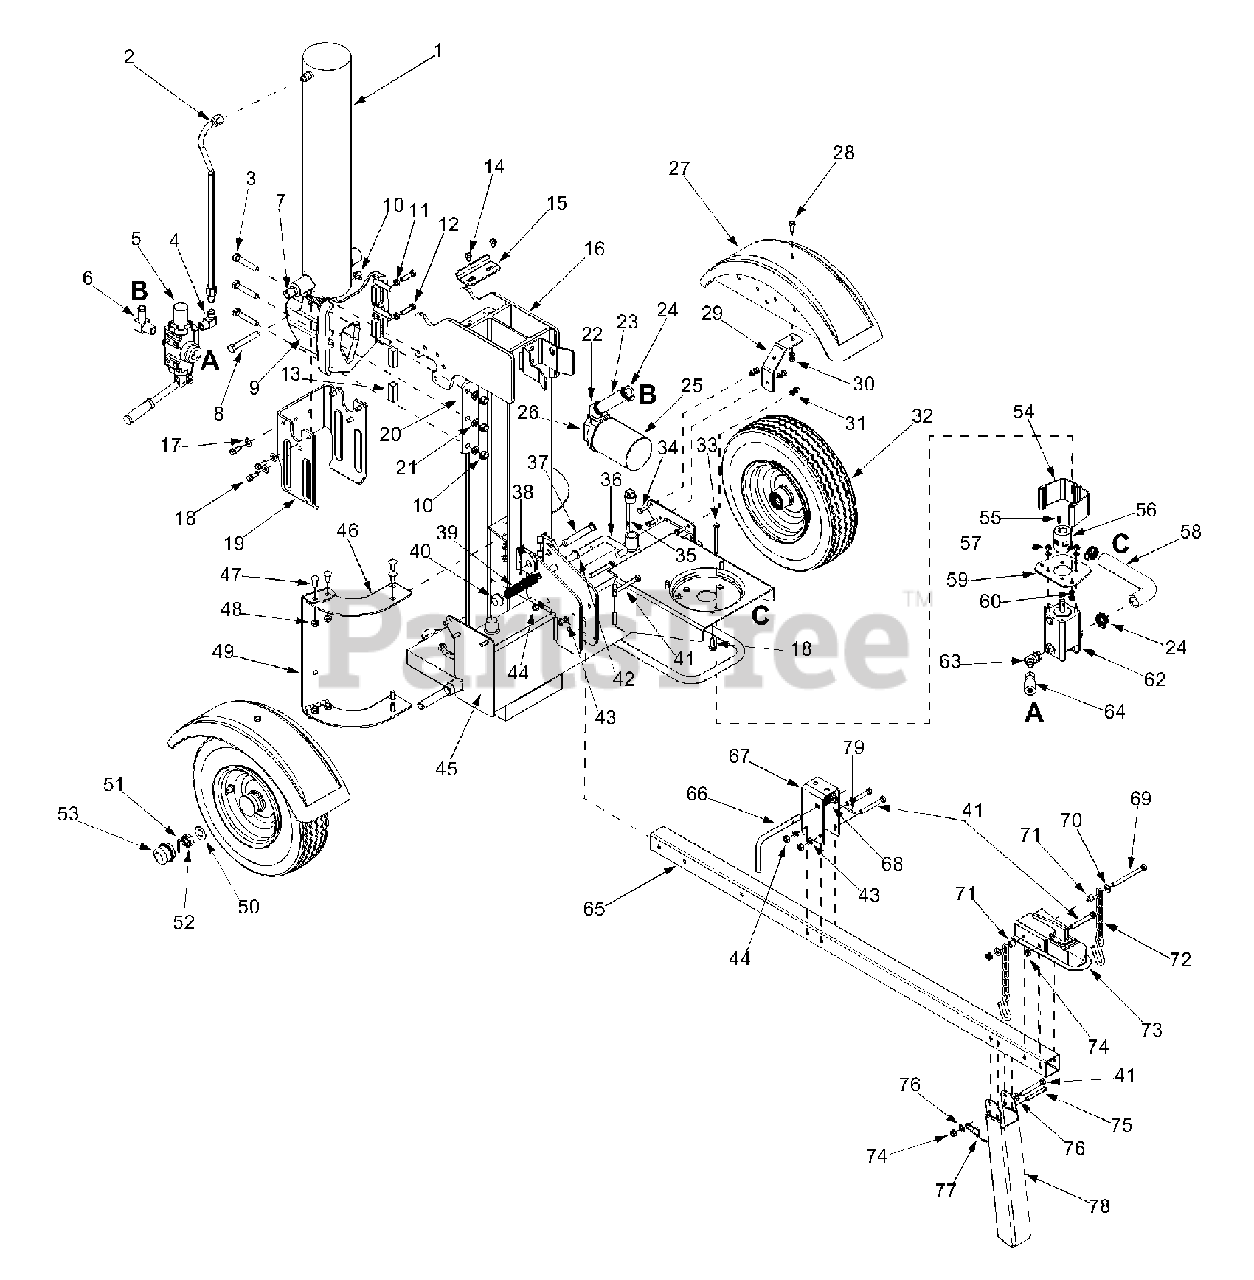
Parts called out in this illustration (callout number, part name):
1	Hydraulic Cylinder
1	Seal Kit 4.5" for Fisher Cylinder 718-0769
1	Kit Seal 4.5" for XINGHUI cylinder 718-0769A
1	Kit Seal 4.5" for ENERGY cylinder 718-0769A
2	Hydraulic Tube
3	Hex Cap Screw 1/2-20 x 2.75
4	90 Degree Solid Adapter
6	Return Elbow
7	Nipple Pipe 1/2-14
8	Hex Cap Screw 1/2-20 x 3.50
9	Wedge Assembly
10	Lock Nut 1/2-20
11	Hex Jam Nut 3/8-24
12	Hex Cap Screw 3/8-24 x 1.5
14	Hex Washer Screw 5/16-18 x .625
17	Flat Washer .406 ID x .875 OD
18	Hex Washer Screw 3/8-16 x 1.0
21	Lock Washer 1/2
22	Adapter 3/4-14
23	Return Hose 3/4" ID x 44" Lg.
24	Hose Clamp 5/8"
25	Oil Filter
26	Filter Housing
27	Fender, Plastic Red
27	Fender, Plastic
28	Hex Washer Screw 5/16-18 x .875
30	Hex Nut 5/16-18
31	Lock Washer 5/16
32	Wheel Assembly
33	Hex Screw 5/16-24 x 3.25
34	Hex Cap Screw 5/16-18 x 1.0
35	Vented Dipstick
36	Lock Rod
37	Clevis Pin
38	Cotter Pin
39	Compression Spring
40	Push Cap
41	Hex Bolt 3/8-16 x 3"
42	Flat Washer .635 ID x .93 OD
43	L-Washer 3/8"
44	Hex Nut 3/8-16
45	Frame Assembly
48	Flanged Lock Nut 3/8-16
50	Flat Washer .760 ID x .500 OD
51	Cotter Pin
52	Slotted Nut 3/4-16
53	Hub Cap
54	Coupling Shield
55	Square Key 3/16" x .75
56	Flexible Coupling
57	Hex Nut 5/16-24
60	Lock Washer 5/16" ID
62	Gear Pump (11gpm)
63	45 Degree Elbow
64	High Pressure Hydraulic Hose
66	Latch Rod
68	Spring Compression
69	Hex Cap Screw 3/8-16 x 4.25
70	Flat Washer .385 ID x .870 OD
71	Spacer .375 ID x .625 OD
72	Chain
73	Coupling Hitch
74	Hex Lock Nut 3/8-16
75	Clevis Pin
76	Flat Washer .375 ID x .738 OD
77	Spring Pin
